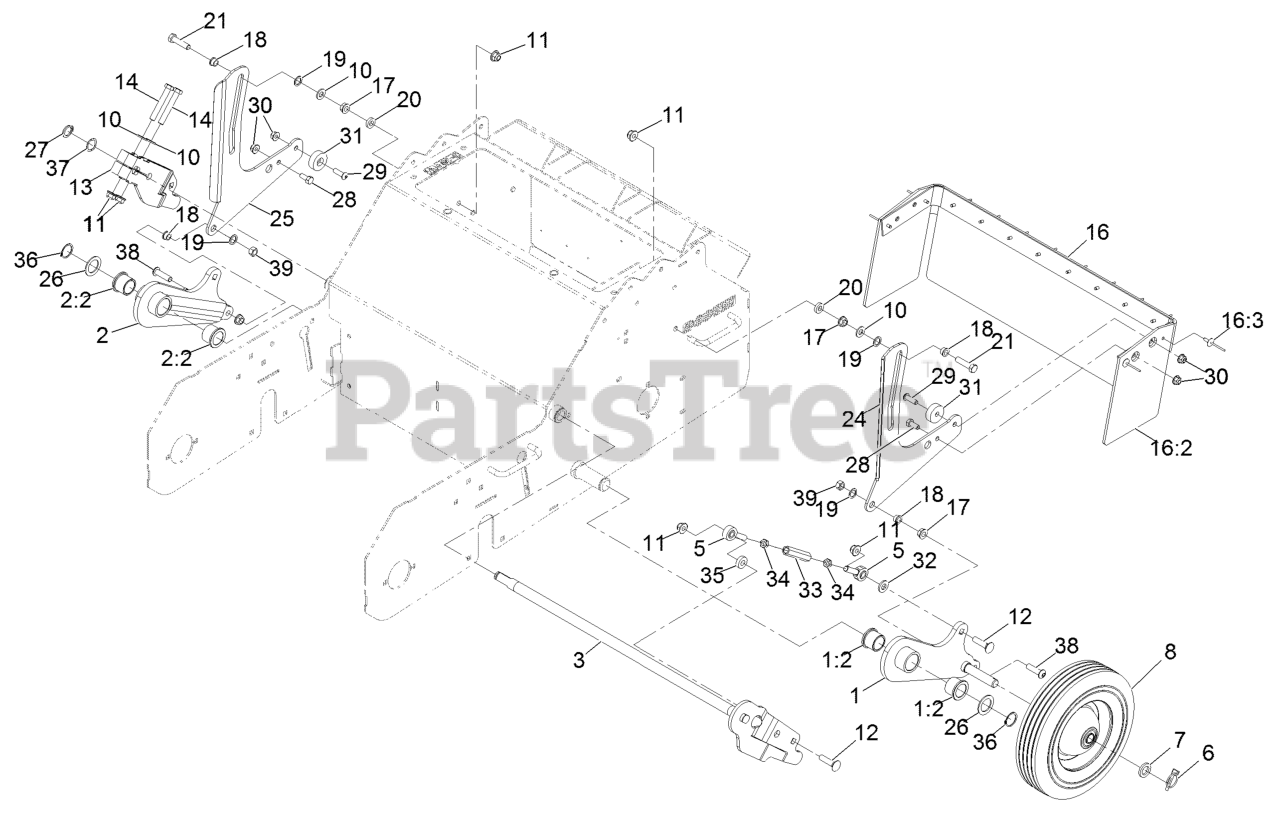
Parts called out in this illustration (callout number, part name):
1	LH WHEEL ARM ASM
1:2	BUSHING-FLANGE
2	RH WHEEL ARM ASM
2:2	BUSHING-FLANGE
3	PIVOT SHAFT ASM
5	BALLJOINT
6	PIN-KLIK
7	SPACER-BEARING
8	WHEEL, TRANSPORT
10	WASHER-FLAT
11	NUT-HF, NI
12	SCREW-CARR
13	ARM-LIFT, RH
14	BOLT-CARR
16	GUARD-FOOT
16:2	FOOT-SHIELD
16:3	RIVET-POP
17	NUT-HHF, WHIZ
18	BUSHING-FLANGED
19	WASHER-NYLON
21	SCREW-HH
24	GUARD-ARM, LH
25	GUARD-ARM, RH
26	WASHER-SPACER
27	RING-RETAINING
28	SCREW-HH
29	SCREW-HSBH
30	NUT-HF, NI
31	GUIDE-ARM, TRAIL
33	ROD-LIFT LINK
34	NUT-HJ
35	SPACER
36	RING-RETAINING
37	WASHER-WAVE
38	SCREW-HSBH
39	NUT-HEX
